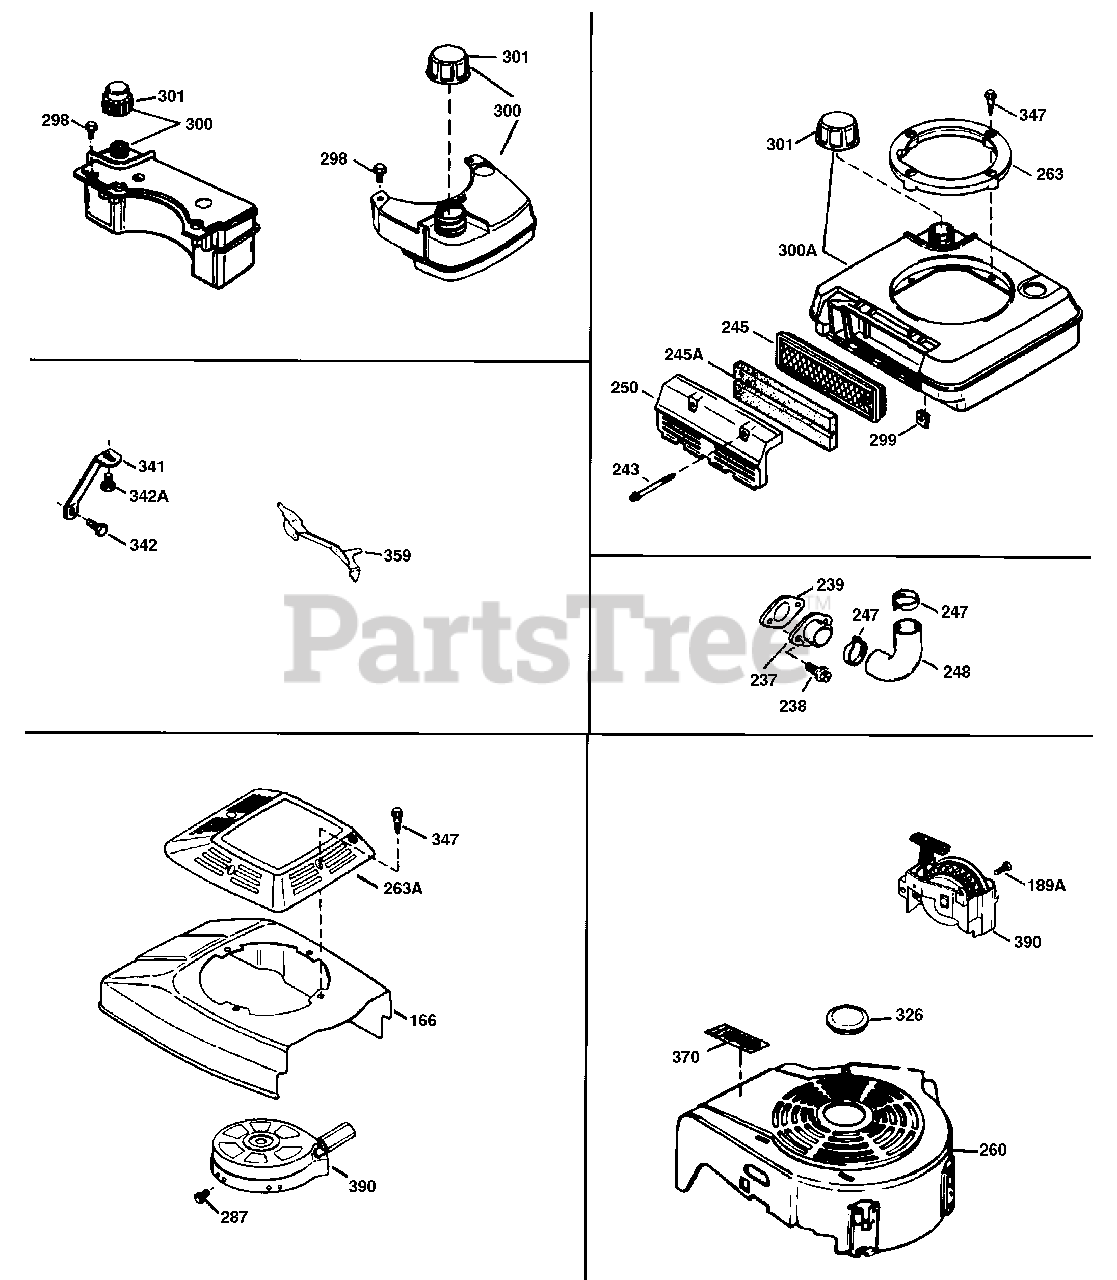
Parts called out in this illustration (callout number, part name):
101A	Spark Plug Shield
189A	Screw, T-30, 1/4-20 x 3/8"
238	Screw, 10-32 x 5/8"
239	* Air Cleaner Gasket
245	Air Filter (Poly) (also available in Packaged Part #740065A)
245A	Breather Filter (Poly) also available in Packaged Part #740065A
250	Air Filter Cover
260	Blower Housing (Red)
263	Recoil Ring (Red)
287	Screw, 8-32 x 21/64"
300	Fuel Tank (Incl. 292 & 301)
301	Fuel Cap
359	Flywheel Guard
390	Rewind Starter (NOTE: This engine co uld have been built with 590738 start er).
